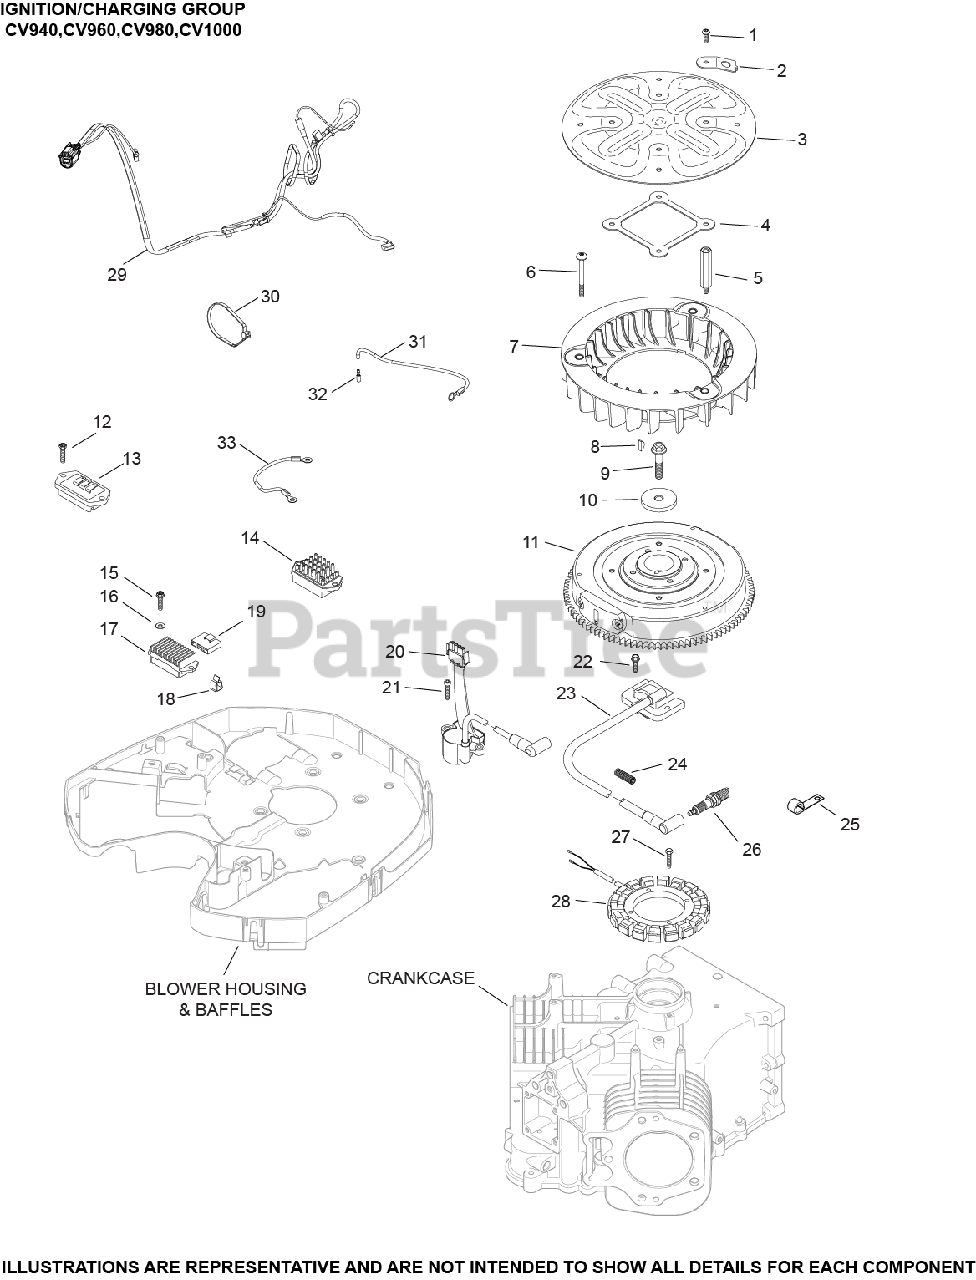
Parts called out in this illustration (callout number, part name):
1	SCREW, BUTTON HD M6X1.0X16 USE 25 086 129-S
2	PLATE, GRASS SCREEN WASHER
3	KIT, GRASS SCREEN
4	STIFFENER, GRASS SCREEN
5	STUD, GRASS SCREEN
6	SCREW, TRS HD M6X1.0X65
7	KIT, FAN AND SPACERS
8	KEY, 3/16" X 5/8"
9	SCREW, FLG M10X1.5X45 - (#25086361S)
10	WASHER, FLAT 13/32"
11	FLYWHEEL ASSEMBLY
12	SCREW, PHL HD #11-16X7/8"
17	REGULATOR, RECTIFIER USE 25 403 29-S
23	MODULE, IGNITION
24	SLEEVE, CORRUGATED
26	PLUG, SPARK
27	SCREW, THREAD FORMING
27	SCREW, THREAD FORMING USE 25 086 472-S
28	KIT, 15 / 20 AMP STATOR
29	HARNESS, WIRING
29	HARNESS, ADAPTER
30	TIE, CABLE
31	LEAD, B+ TO STARTER SOLENOID
